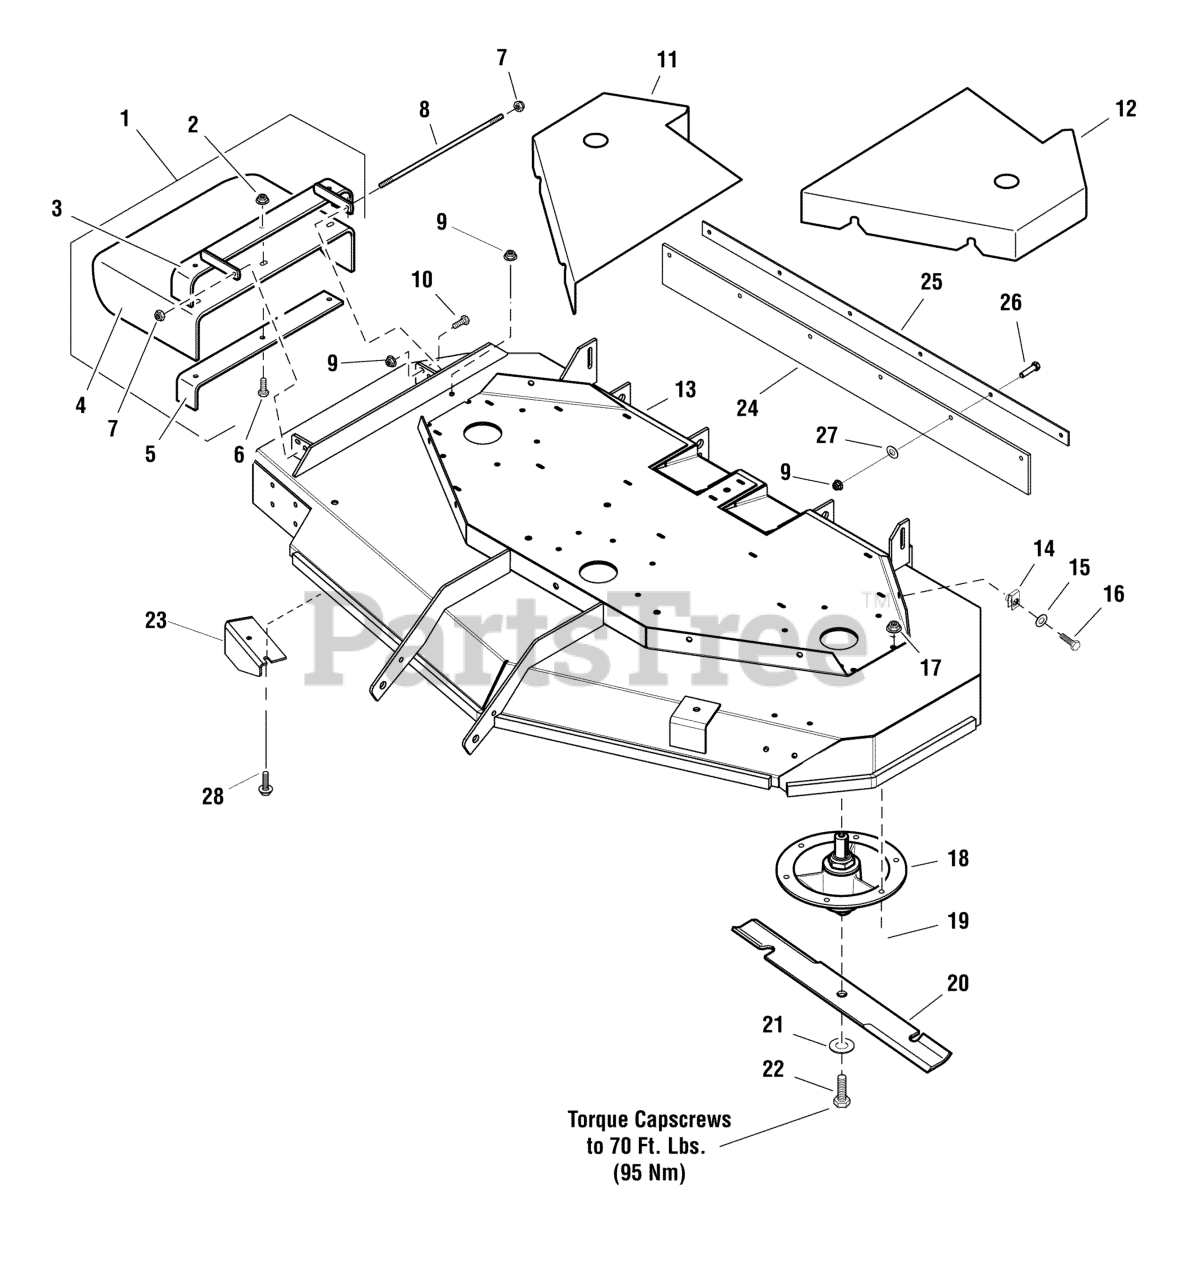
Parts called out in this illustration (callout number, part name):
1	PURCHASE INDIVIDUAL REPLACEMENT PARTS
2	NUT, 3/8 - 16 HEX NYLOCK FLANGE
3	WELD, FRAME CHUTE, 61 - BLK
4	CHUTE, DISCHARGE, BEND RUBBER (SV)
5	SUPPORT, DISCHARGE CHUTE, 61/72 - BLK
6	BOLT, 3/8-16 X 1-1/4" GD5 CZ
7	NUT, 5/16-24 HEX NYLON LOCK
8	ROD, MOUNT, CHUTE, 61, CZ
9	NUT, 5/16-18 HEX NYLOCK FLANGE NUT
10	BOLT, 5/16-18 X 3/4 GD5
11	SPINDLE COVER - RH
12	GUARD, 61, LH - RED
13	DECK SHELL W/DECALS, 61 (5407544B)
13	DECK SHELL W/DECALS,3100-61,EXP,5407544B
14	BODY CLIP, 5/16-18-7GA MATERIAL
15	WASHER, 5/16" SAE
16	BOLT, 5/16-18 X 3/4 GD5
17	NUT, 3/8 - 16 HEX NYLOCK FLANGE
18	SPINDLE ASSEMBLY
19	BOLT, 3/8-16 X 1-1/4, FLANGE, GD 5, CZ
20	BLADE SET, 61 DECK (3)
21	WASHER, BLADE BOLT, 9/16" F436, CZ
22	BOLT, 5/8-11 X 1-3/4 GD8
23	PLATE, DEFLECTOR - BLK
24	FLAP, STRIPER, 61 DECK, IS3100 S200X
25	PLATE, SUPPORT - BLK
26	BOLT, 5/16-18 X 1" GRD5 YZ
27	5/16" PUSH-ON NUT RETAINER, STL, CZ
28	BOLT, 5/16-18 X 3/4, CARRIAGE, GD5, CZ
